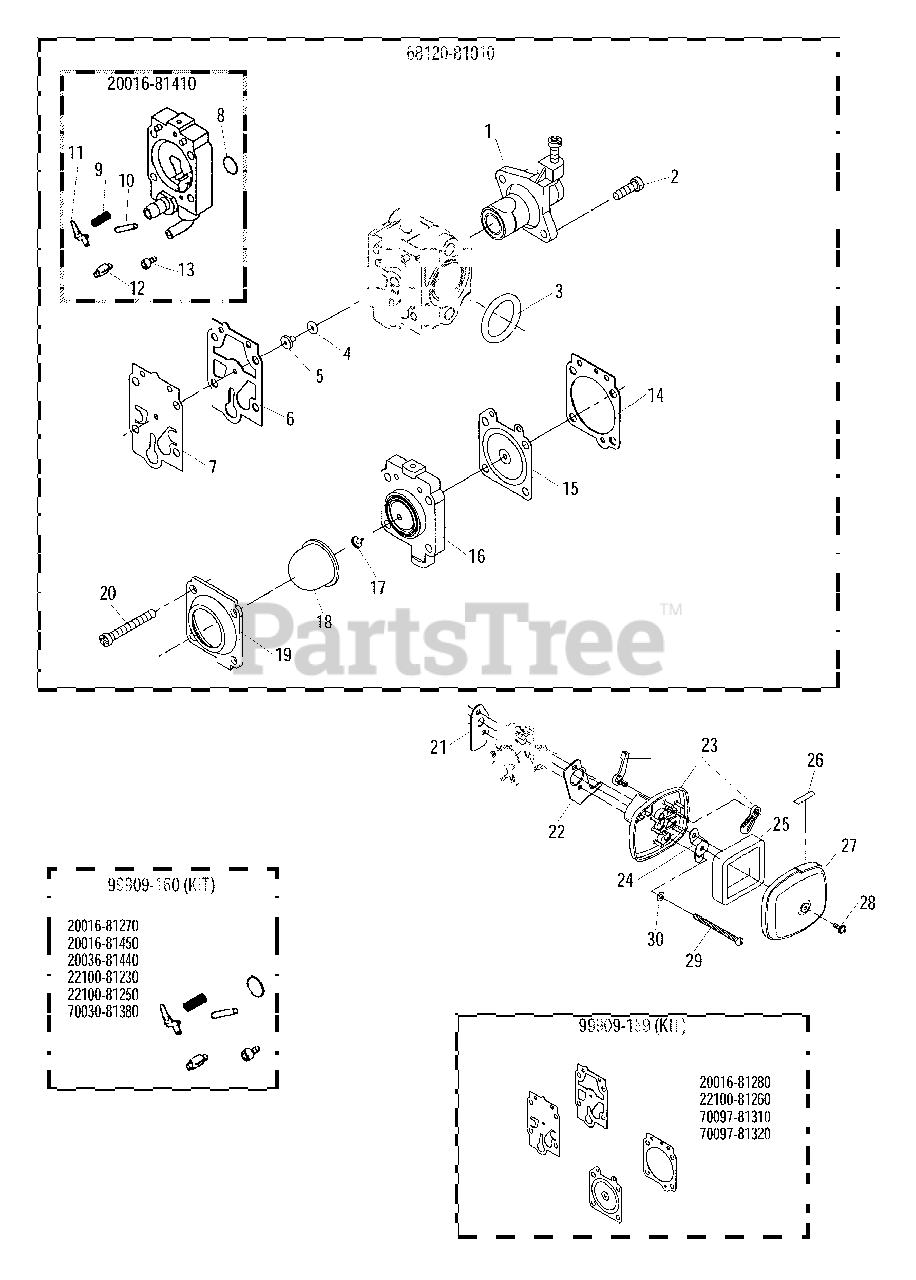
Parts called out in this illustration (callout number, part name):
1	THROTTLE VALVE ASSY
2	SCREW
3	O-RING 15
4	O-RING
5	JET, MAIN #40
6	GASKET, PUMP
7	DIAPHRAGM, PUMP
8	SCREEN, FUEL INLET
9	SPRING, METERING LEVER
10	PIN, METERING LEVER
11	LEVER, METERING
12	VALVE, INLET NEEDLE
13	SCREW
14	GASKET, METERING DIAPHRAGM
15	DIAPHRAGM, METERING
16	BODY ASSY, PURGE
17	VALVE, CHECK
18	BULB, PURGE
19	RETAINER, PURGE BULB
20	SCREW
21	GASKET
22	HOLDER, CABLE
23	BASE ASSY, AIR FILTER
24	BRACKET
25	FILTER
26	LABEL, CHOKE
27	COVER, AIR FILTER
28	SCREW
29	SCREW
30	WASHER, FLAT 5.5×10×0.8
20016-81410	BODY ASSY, PUMP
68120-81010	CARBURETOR
99909-159	GASKET / DIAPHRAGM KIT
99909-160	VALVE KIT, INLET NEEDLE
